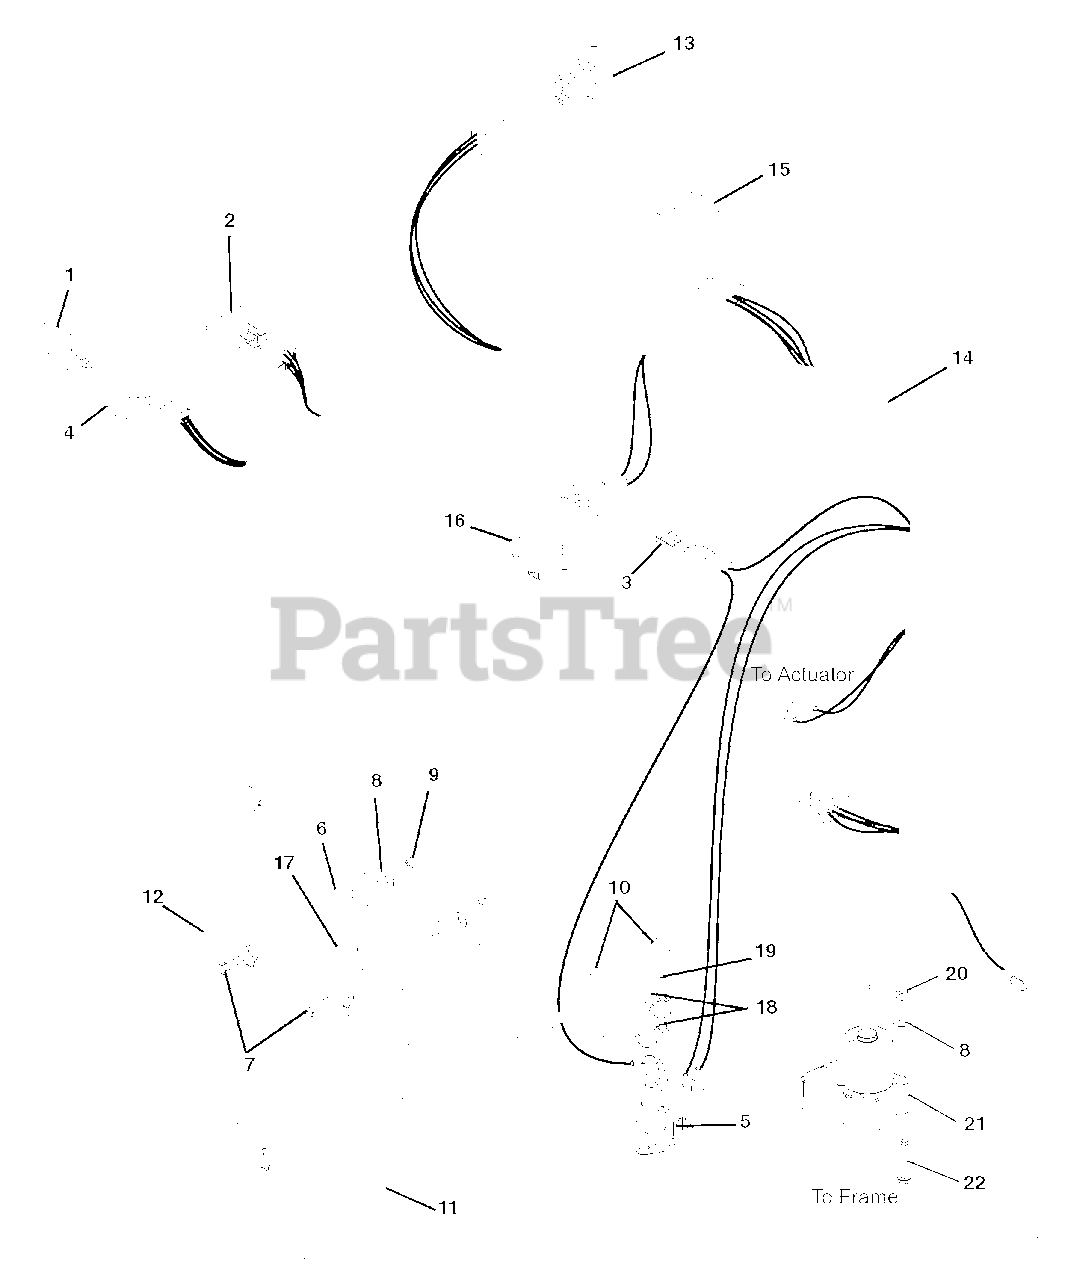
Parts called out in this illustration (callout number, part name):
1	Key with Cap
2	Relay
3	Fuse, 30 AMP
4	KEYSWITCH-IGNITION 3 POS
5	Solenoid
7	Bolt, Hex .25-20 x .75 Grade 5
8	Washer, Flat Steel .281 x .62 x .065
9	Nut, KEPS .250-20
10	Boot, Eyelet Terminal
11	Cable, POS
12	Ground Cable
13	Switch, Clutch With Retainer
14	Harness, Wiring BBZ
15	Switch, Double Pole N.O. / N.O.
16	Switch, Snap Mounting (N.O.)
17	Insulator
18	Washer, Locking .31
19	Nut, Jam .31-24
20	Nut, .25-20 Nyloc Flange
21	Actuator-NORAM PAC 2"
22	Bolt, Hex .25-20 x 2.50 Grade 5
